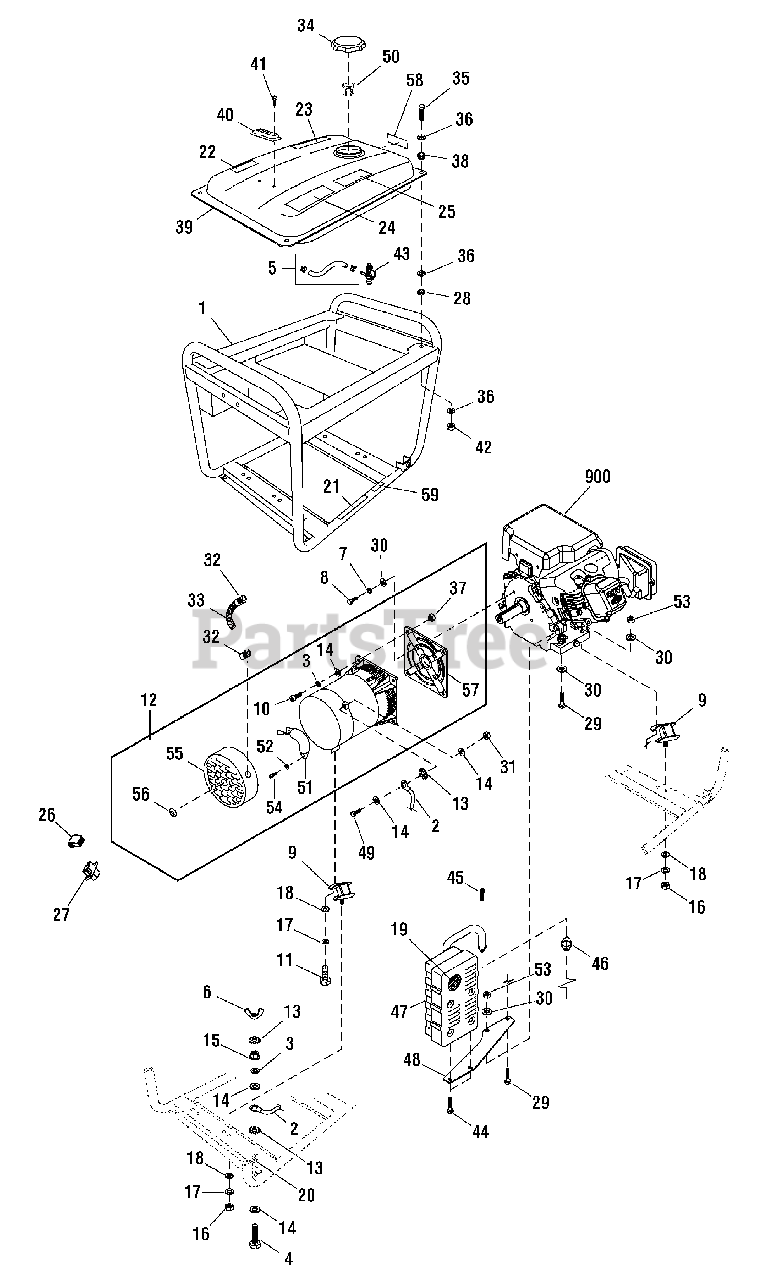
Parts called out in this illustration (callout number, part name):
1	CRADLE
3	* WASHER, Lock, M8
4	* BOLT, M8 x 30
5	KIT, Fuel Hose
7	* WASHER, Lock, M8
8	* CAPSCREW, Hex Head, 5/16-24
9	MOUNT, Vibration
10	* CAPSCREW, Socket Head, M8 x 30
11	* CAPSCREW, Hex Head
13	* WASHER, M8
14	* WASHER, Flat, M8 x 16
15	* NUT, Hex, M8
16	* NUT, M10
17	* WASHER, Lock, M10
18	* WASHER, Flat, M10
27	WIRE END SEAT, WHT
29	* CAPSCREW, Hex Head, M8 x 35
30	* WASHER, Flat, M8 x 16
31	* NUT, Nylon, M8
34	CAP, Fuel
35	* SCREW, M6 x 30
36	* WASHER, Flat, M6 x 24
37	* NUT, M8
39	TANK, Fuel
41	* SCREW, M5 x 10
42	* NUT, Nylon, M6
43	VALVE, Fuel
44	* CAPSCREW, Hex Head, M6 - 1.0 x 12 with LW
45	* CAPSCREW, Socket Head, M6 - 1.0 x 20
46	GASKET
49	* SCREW, M8 x 25
53	* NUT, Nylon, M8
55	COVER, Rear Bearing
59	DECAL
900	** ENGINE
